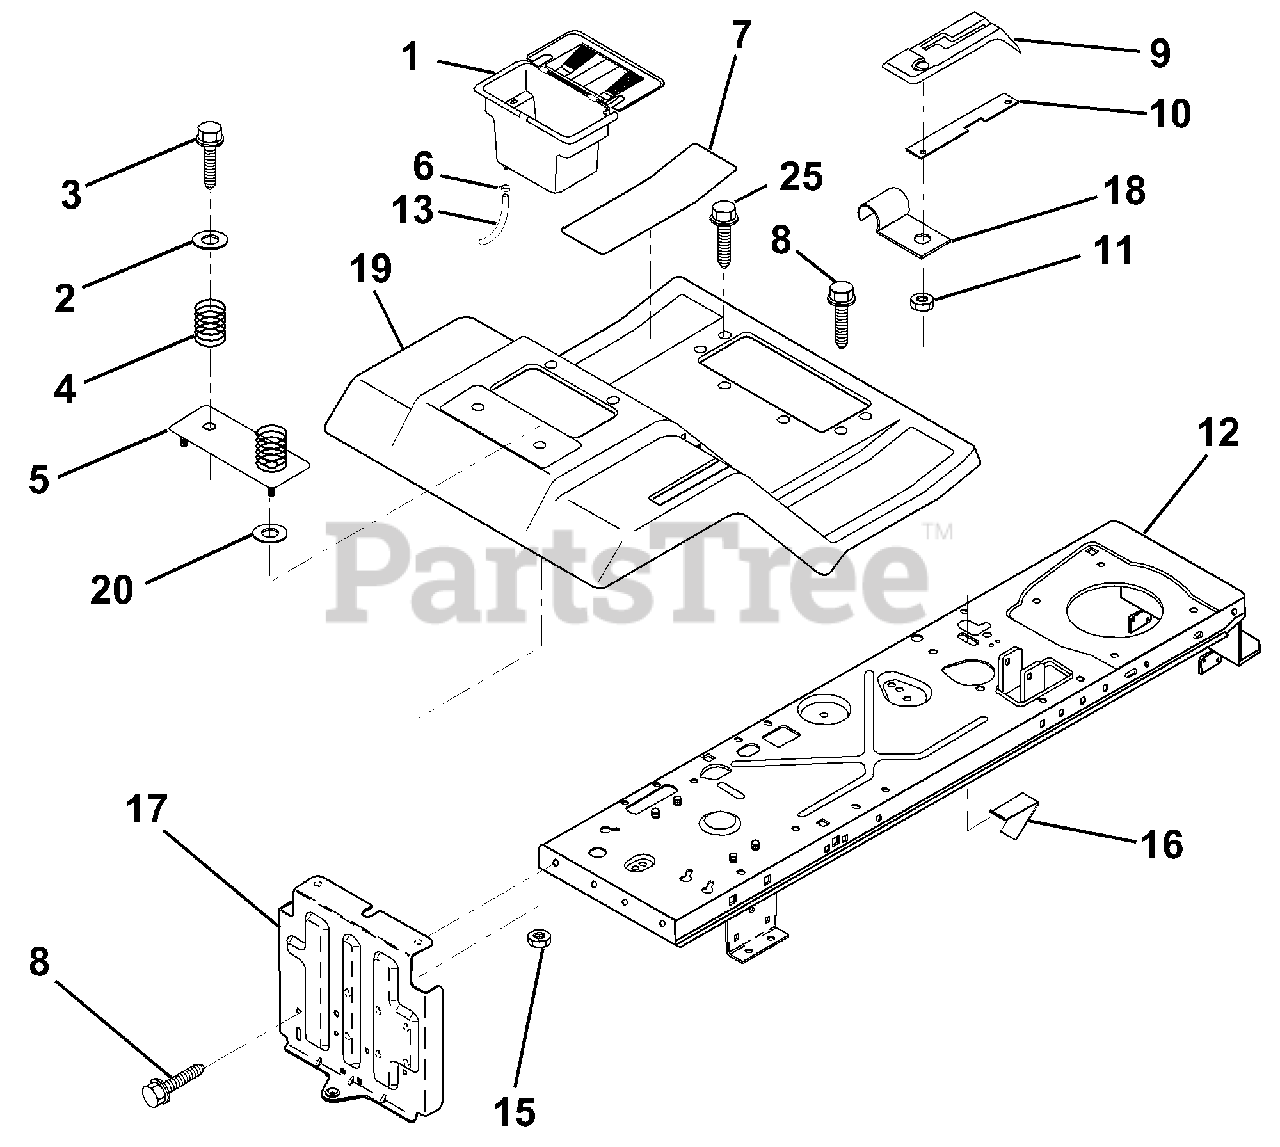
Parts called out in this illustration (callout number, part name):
1	Case, Battery
2	Washer 13/32 x 1-1/4 x 12 Ga.
3	Screw, Hex Wsh. Thrdrol. 3/8-16 x 3/4
4	Spring, Compression, Seat
5	Plate, Asm. Battery
6	Clamp, Hose
7	Pad, Footrest
8	Screw, Hex Wsh Thdrol. 5/16-18 x 3/4
9	Console, Shift Control
10	Bar, Shift Lock
11	Nut, Self-Thrd., Wsh. Head 3/16
12	Assembly, Frame
13	Tube, Battery Drain
15	Nut, Keps Hex 1/4-20 UNC
16	Switch Actuato
18	Clip, Insulated
19	Fender/Footrest
20	Washer 9/32 x 7/8 x 13 Ga.
25	Screw Hex Wsh Thdroll 5/16-18 x 1
